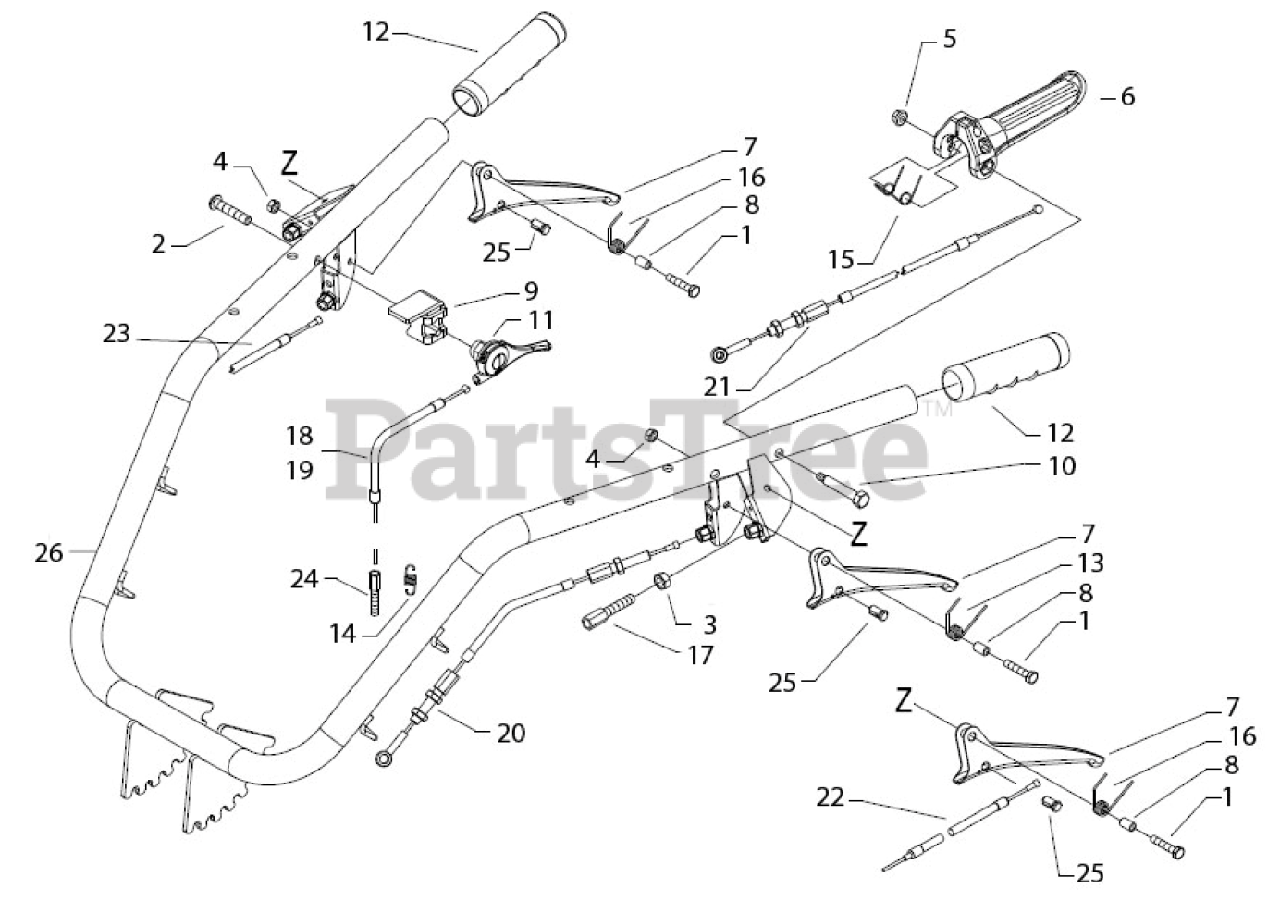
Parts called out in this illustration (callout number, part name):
1	SCREW TE M6X25
2	SCREW TBCEI M8X40
3	NUT M8
4	SELFLOCK NUT M6
5	SELFLOCK NUT M6
6	OPC LEVER
7	LEVER
8	SPACER
9	PANEL
10	LEVER PIN
11	LEVER, THROTTLE
13	SPRING
14	SPRING
15	SPRING
16	SPRING
17	ADJUSTING SCREW
18	CABLE, THROTTLE KD440
19	CABLE, THROTTLE GX390
20	CABLE, CLUTCH
21	CABLE, OPC
22	CABLE, BRAKE
23	CABLE, STEERING RELEASE
24	ADJUSTING SCREW
25	CABLE CLAMP
26	HANDLE BAR
